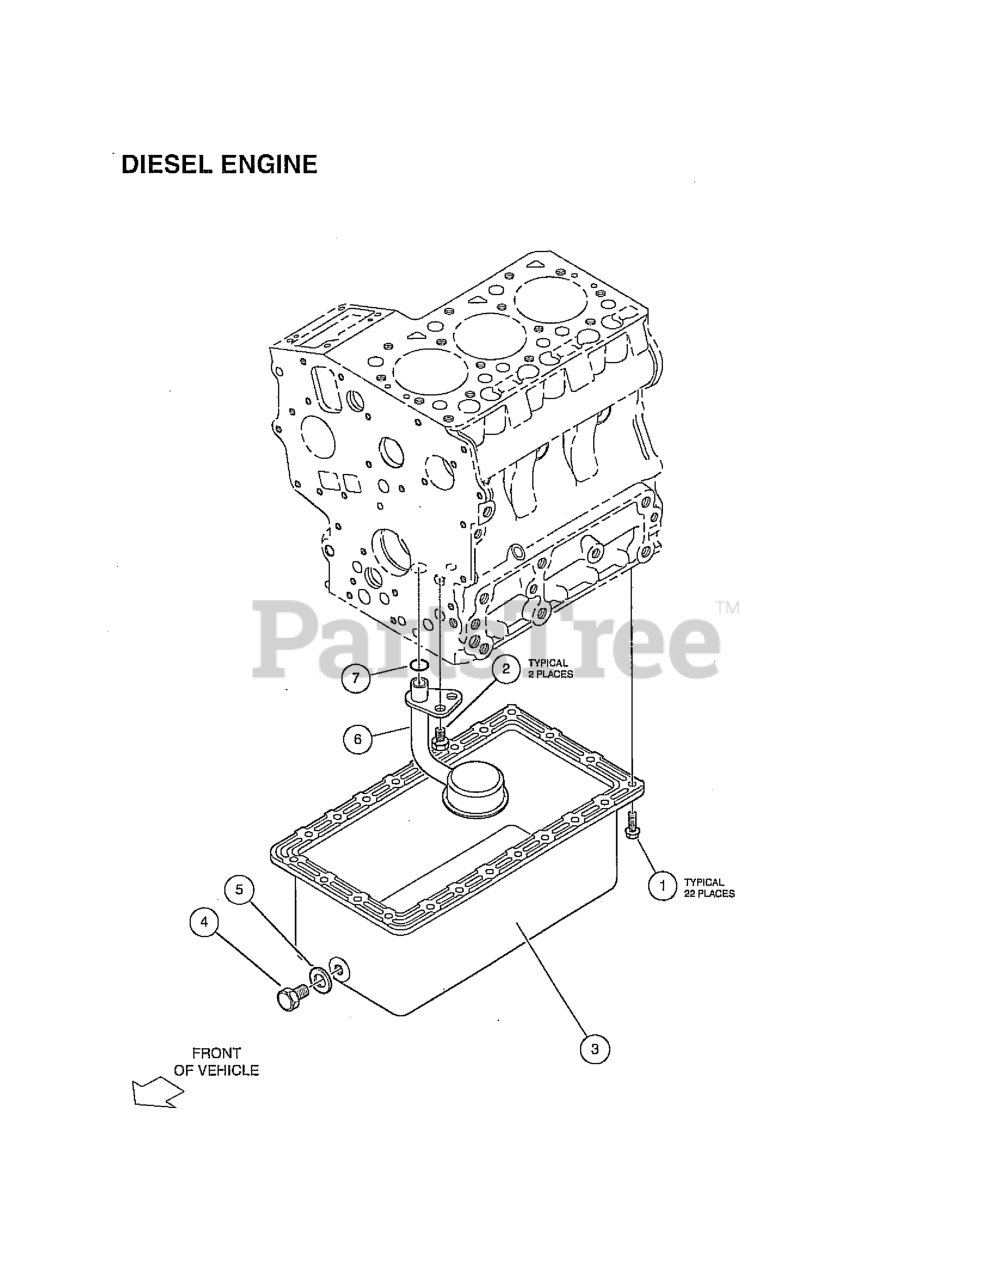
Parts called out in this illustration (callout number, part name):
1	BOLT, M6 X 1 X 14
2	BOLT, M8 X 1.25 X 15
3	COMP, OIL PAN
4	PLUG, DRAIN, M12 X 14
5	GASKET, 20 X 13
7	O RING, 20 X 17
